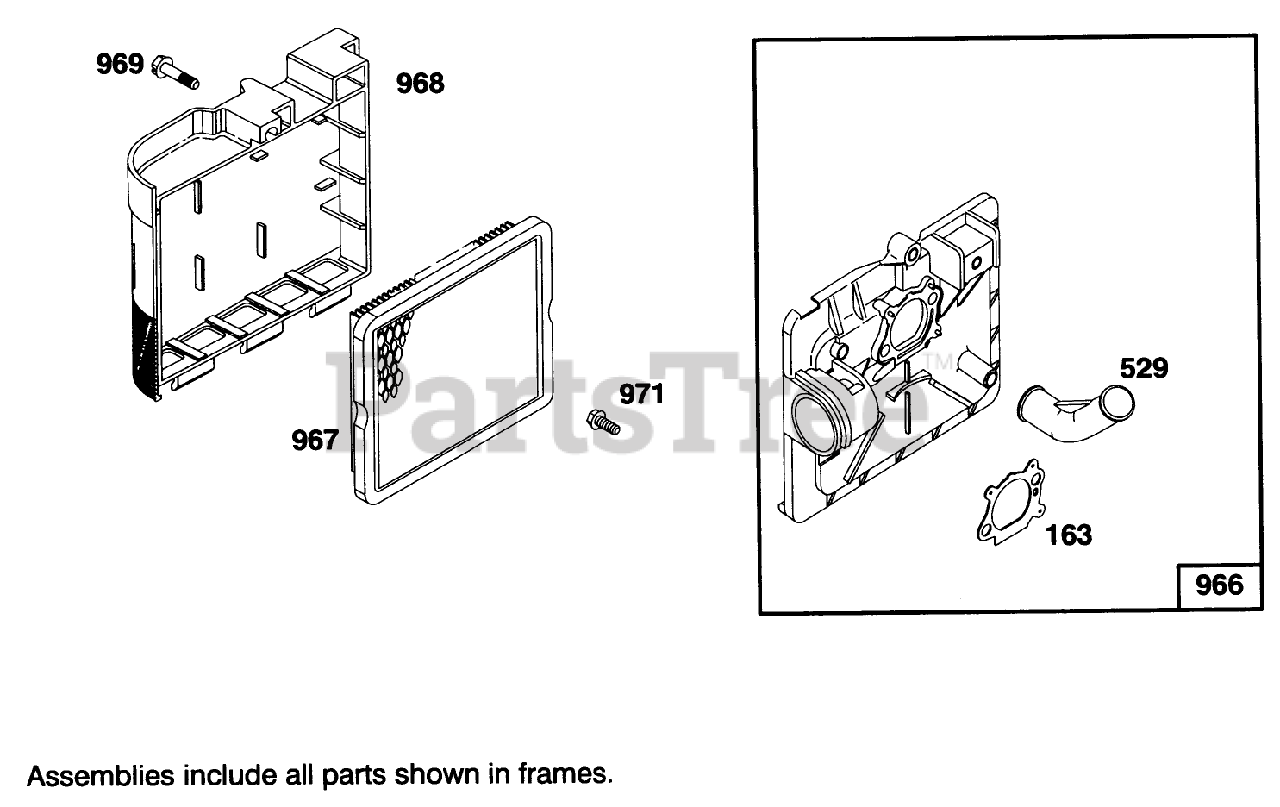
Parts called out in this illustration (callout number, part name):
163	Gasket-Cleaner, Air
529	Grommet
966	Base-Primer, Air Cleaner
967	Filter-Air Cleaner, Cartridge
968	Air Cleaner Cover
969	Screw-Cover Mt.
971	Screw-Air Cleaner
